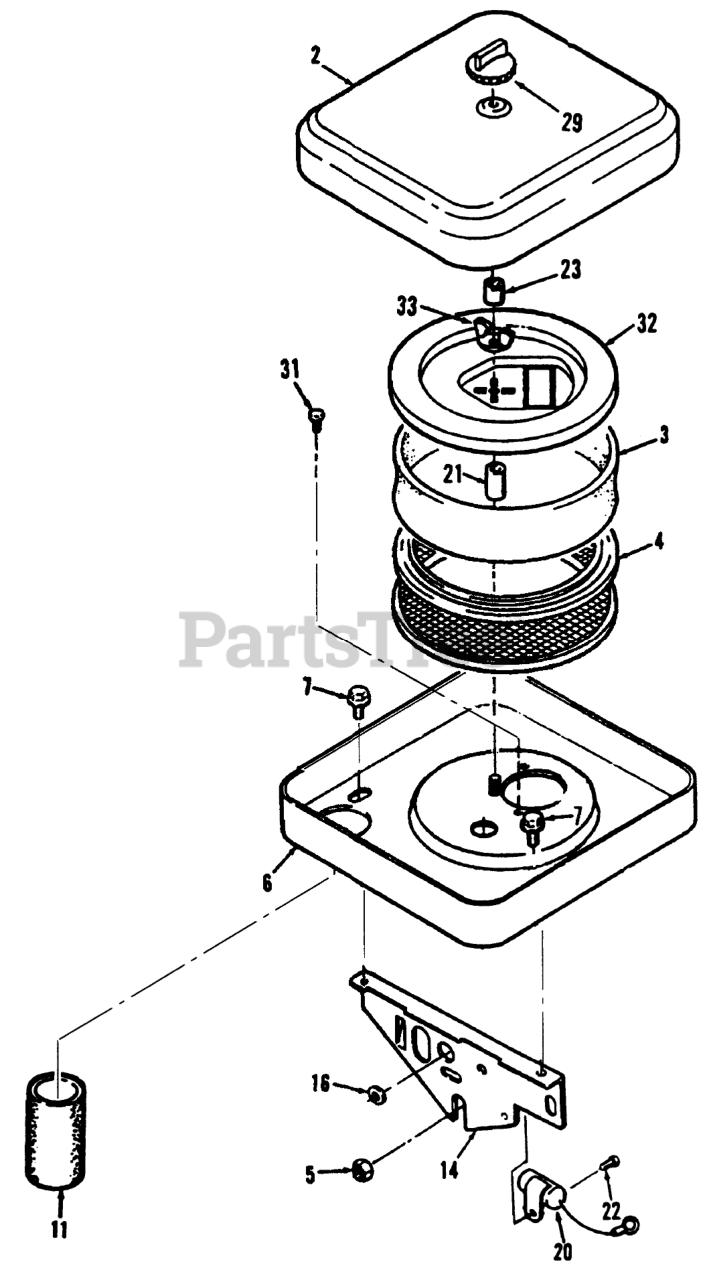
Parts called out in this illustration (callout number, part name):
2	CHROME-AIR CLEANER
3	AIR CLEANER ELEMENT
4	Element-Air Cleaner
5	Washer
6	AIR-CLEANER HOUSING
7	SCREW-TAPPING
11	AIR INTAKE TUBE
14	SUPPORT-AIR CLEANER
16	Grommet
20	Condenser
21	SPACER-1" LG
22	SCREW #10-32 X 5/8
23	SPACER-RUBBER
31	MACHINE SCREW
32	Cover-Element
33	1/4-20 WING NUT
